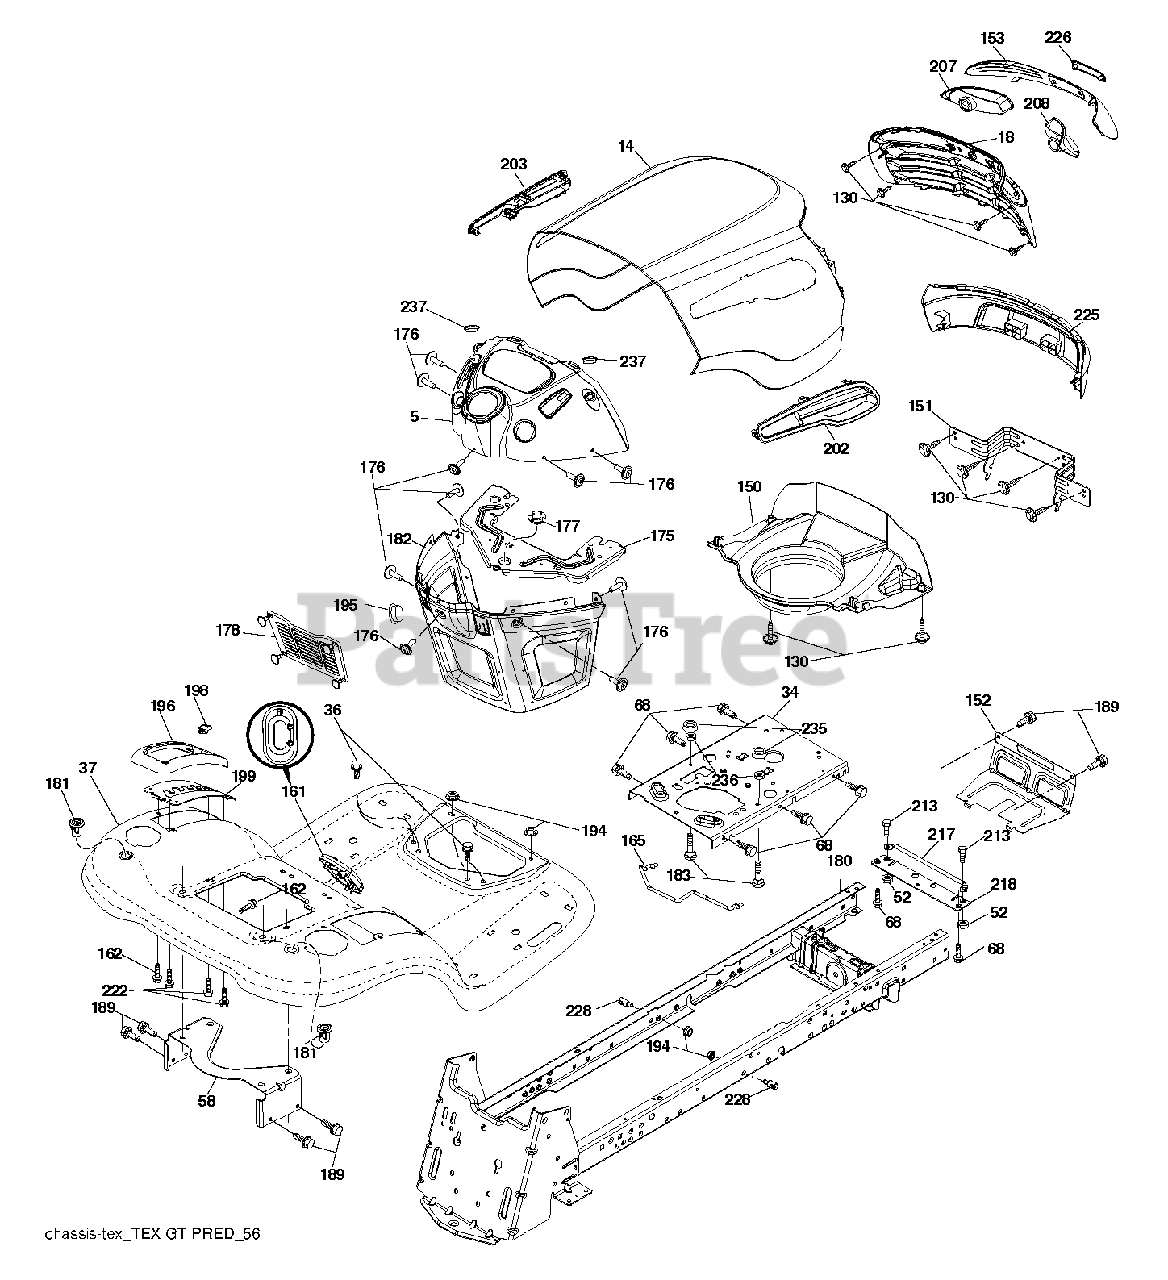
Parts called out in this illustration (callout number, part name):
5	DASH.UPPER.PRED.YT.SQ.CHOKMATC
14	HOOD.PNT.PREDATOR.YT/GT.667
18	GRILLE.SVC.PREDATOR.YT.TEX
34	Engine Welded Chassis Plate
36	SCREW 5/16"
37	FENDER.PNT.TXGT.ERG.SD.FIL.667
52	LOCKNUT
58	BRKT.SUPPORT.FNDR/TANK
130	SCREW.#10 X 0.750.BOS THREAD
150	AIR.DUCT.HOOD.PREDATOR.NO.RING
151	Pivot Predator Bracket
152	SHIELD BROWNING
153	LENS.BAR.PREDATOR.YT.CLEAR
161	CONSOLE.FUEL.WINDOW.STGT.BLACK
162	SCREW.HI-LO.CONSOLE
165	SUPPORT.TANK.REAR.W/TE
175	PLATE.CROSSMEMBER.HUSQ
176	SCREW.#10-24X5/8.RN.QU
177	BUSHING,STEERING
178	CARGO.ASM.NET.TXGT.W/C
180	CHASSIS.GT.SLOPED.DRAWBAR.
181	FEND/FTRST.PCH.CPH.NFW
182	DASH.LOWER.COMMON.12V.ADAPTOR
183	BOLT.5/16-18X1-1/4 FULL THD
189	SCREW
194	NUT LOCK HEX FLANGE 5/16-18
195	PLUG.HOLE.DASH.LOWER.12V.BLK
198	INDICATOR.DECK.LIFT.RED
199	PLATE DECK LIFT
213	BOLT
217	ROD.PIVOT.HOOD
218	X-PIECE.HOOD.STOP.NON/
222	SCREW.1/4-20X5/8
225	BUMPER.GRILLE.PREDATOR.YT.667
226	LOGO.PREDATOR GT.TEX.BLACK
228	STUD.FASTNER.W/ANTI-ROTATE
235	SPACER FENDER
236	NUT.CENTERLOCK.5/16-
237	PLUG.MOUNT.CARGO.BLK
